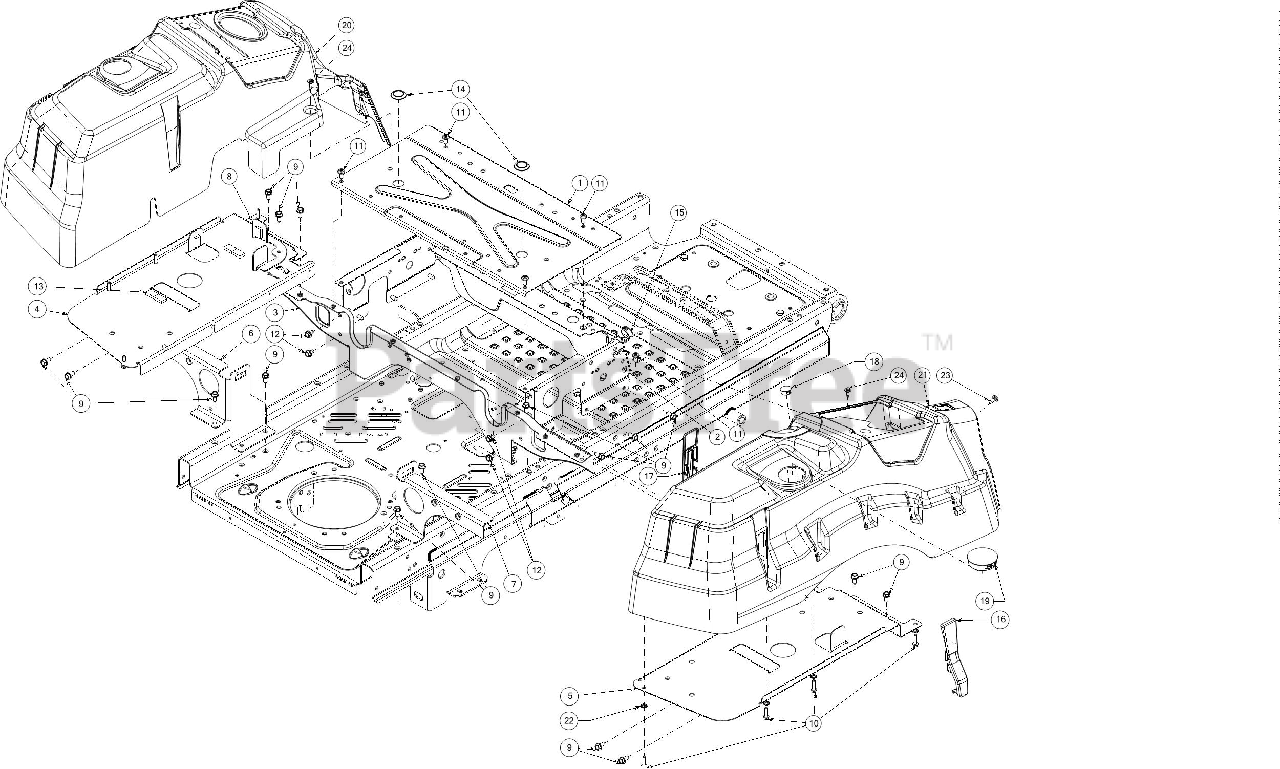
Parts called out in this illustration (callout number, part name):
1	SEATBOX TOP PLATE
2	SEAT FRAME
3	REAR SEATBOX BRACE
4	TANK SUPPORT PLATE (LH)
5	TANK SUPPORT PLATE (RH)
6	REAR BRACKET SUPPORT (LH)
7	REAR BRACKET SUPPORT (RH)
8	REAR TANK BRACKET
9	SCREW 5/16-18 x .750
10	SCREW 5/16-14 x 1
11	SCREW 5/16-18 x .750
12	SCREW 5/16-18 x .500
13	FOAM TAPE .625 WIDE x .25 THK BULK
15	PLASTIC PLUG
16	CONSOLE PLUG (RH) OUTER
17	CONSOLE PLUG (RH) INNER
18	CONSOLE PLUG (RH)
19	FUEL NECK PLUG
20	CONSOLE (LH) 2.25" CAP
21	CONSOLE (RH) 2.25" CAP
23	TORX SHOULDER SCREW 1/4-20
24	SHOULDER SCREW M6-1 .368 X.115
